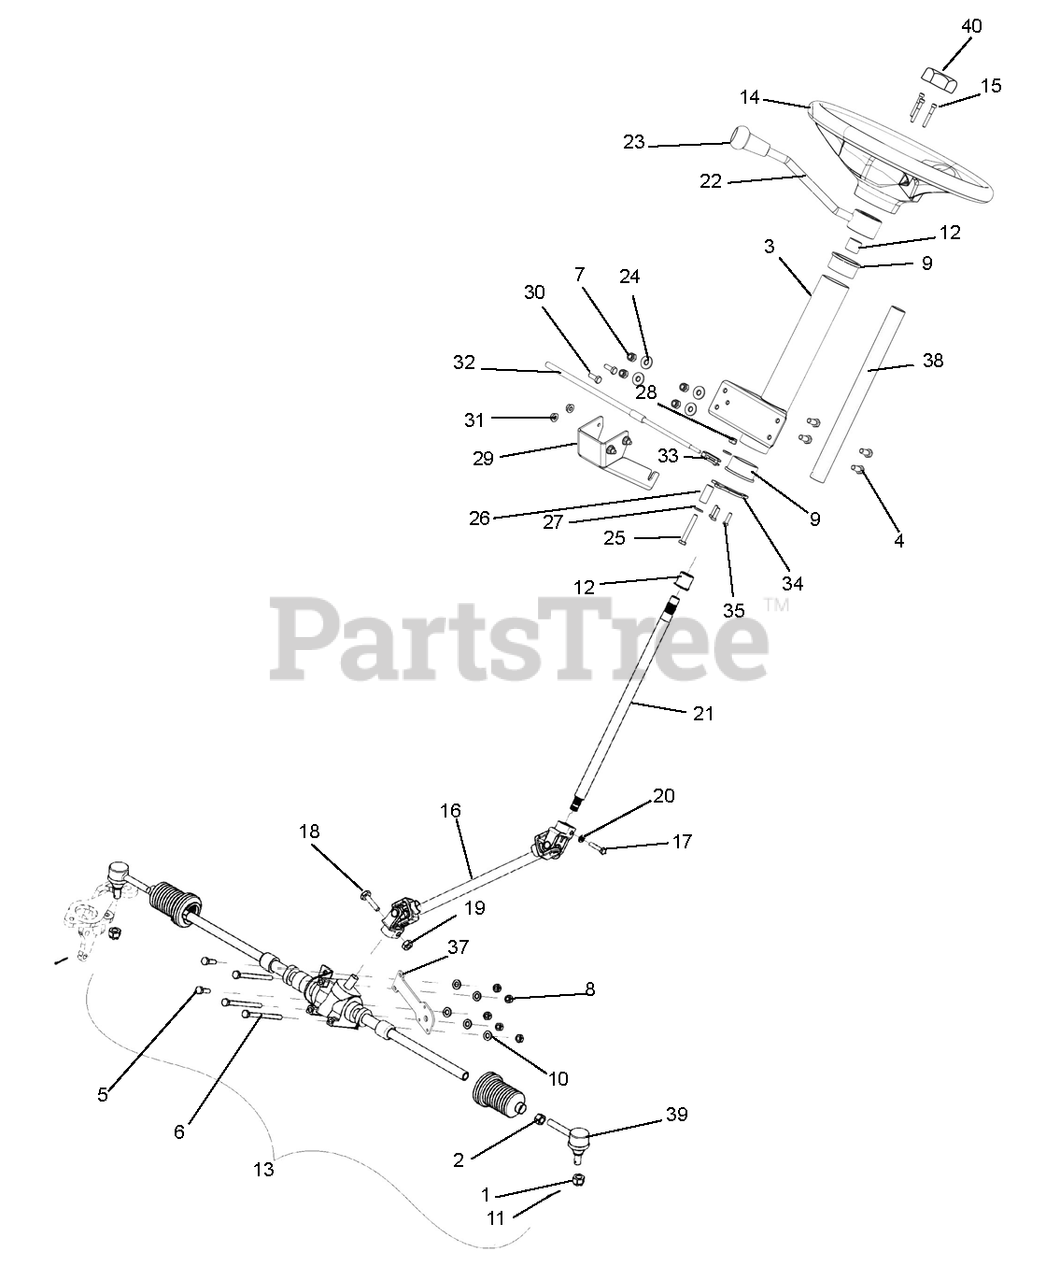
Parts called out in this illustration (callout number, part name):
1	NUT-HEX-SLOTTED M12X1.25 YWZC
2	NUT-HEX M14-1.50 GR8.8 YWZC
3	WLDT,STEERING COLUMN,BLK
4	@BLT-HEX .31-18X.75 GR5 YWZC
5	@BLT-HEX .31-18X1.50 GR5 YWZC
6	@BLT-HEX .31-18X4.50 GR5 YWZC
7	@NUT-LK-NYL .312-18 YWZC
8	@NUT-LK-TOP-FLG .31-18 YWZC
9	BUSHING, NYLON
10	@WSHR-FL-STL.38X.875X.083 YWZC
11	@PIN-CTR .09X1.00 EXTPRSQCT YZ
12	BUSHING, NYLON
13	RACK & PINION ST
14	STEERING WHEEL, 3 SPK CONTOUR
15	BOLT, 10-24X1.25 SOC GR5 Y
16	STEERING SHAFT TRUCK
17	MVL BOLT FOR 840-093C
18	HHCS M10X1.5X35 PLT
19	NUT-LK-NYL M10-1.5 YWZC
20	MVL SPRING WASHER FOR 840-093C
21	UPPER STEERING SHAFT TRUCK ASM
22	WLDT,COLUMN SHIFT LEVER
23	DASH SHIFTER KNOB
24	@WSHR-FL-STL.38X.875X.083 YWZC
25	@BLT-HEX .25-20X2.00 GR5 YWZC
26	SHIFT STOP
27	@WSHR-FL-STL.281X.62X.065 YWZC
28	@NUT-LK-NYL .250-20 YWZC
29	CABLE BRKT,SHIFTER,BLK
30	@BLT-HEX .25-20X.75 GR5 YWZC
31	@NUT-SPNLK-FLG .25-20 YWZC
32	SHIFT CABLE (DASH)
33	YOKE 10-32 W/ LOCK
34	CAM, COLUMN SHIFTER
35	SHCS #10-24 X .750
37	SPACER,STEERING
38	WLDT, COLUMN SHIFTER
39	TIE ROD END 826-399C
40	NUT HEX M16X2.00X8MM THK PLT
